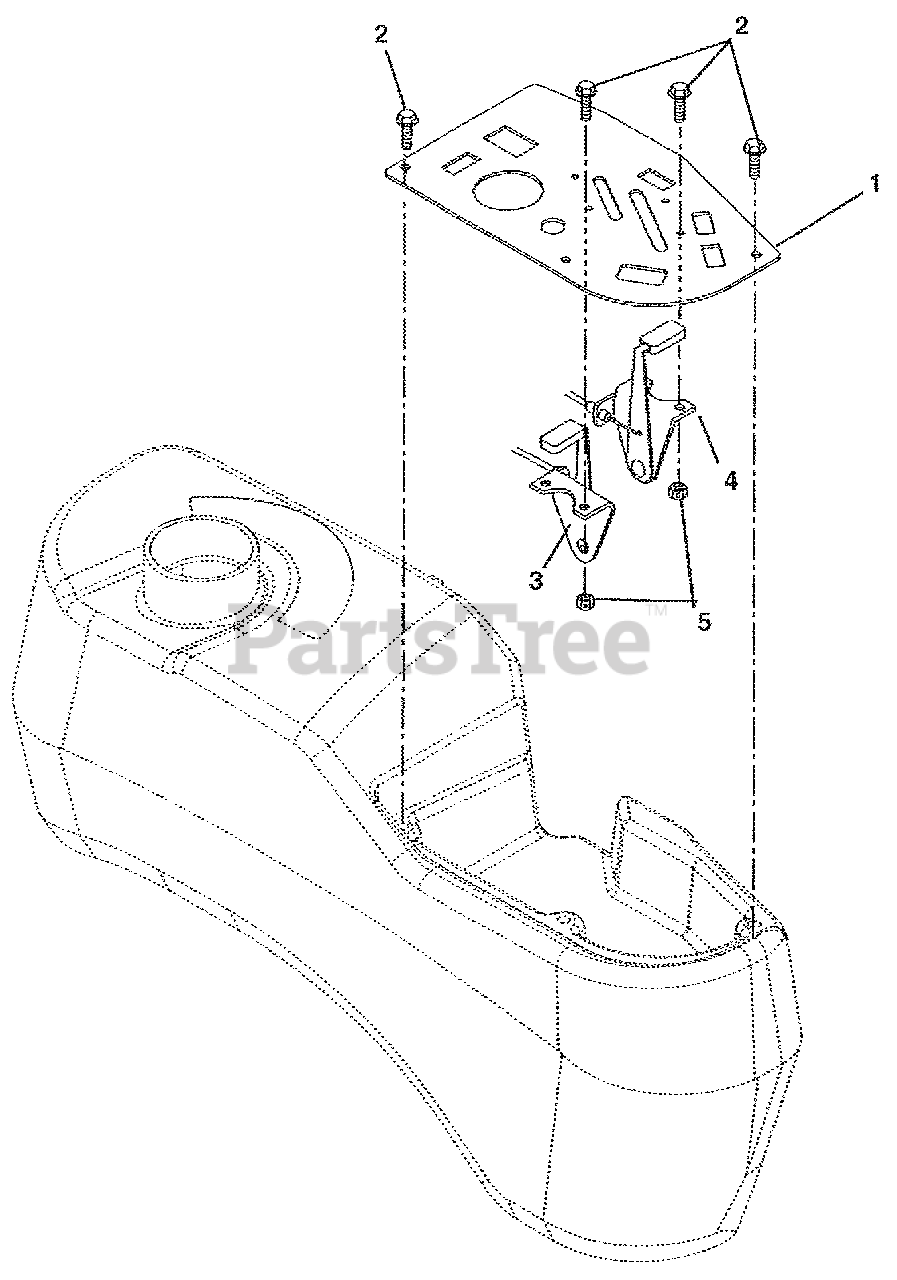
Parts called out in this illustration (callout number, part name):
1	Panel, Control
2	Screw, Machine 10-24 x .50 Hex Washer Head (066, 067, 068, 070, 071, 072)
3	Throttle, Control
4	Choke Control (066, 067, 070)
5	Nut, Locking Nylon 10-24 with Insert (066, 067, 068, 070, 071, 072)
